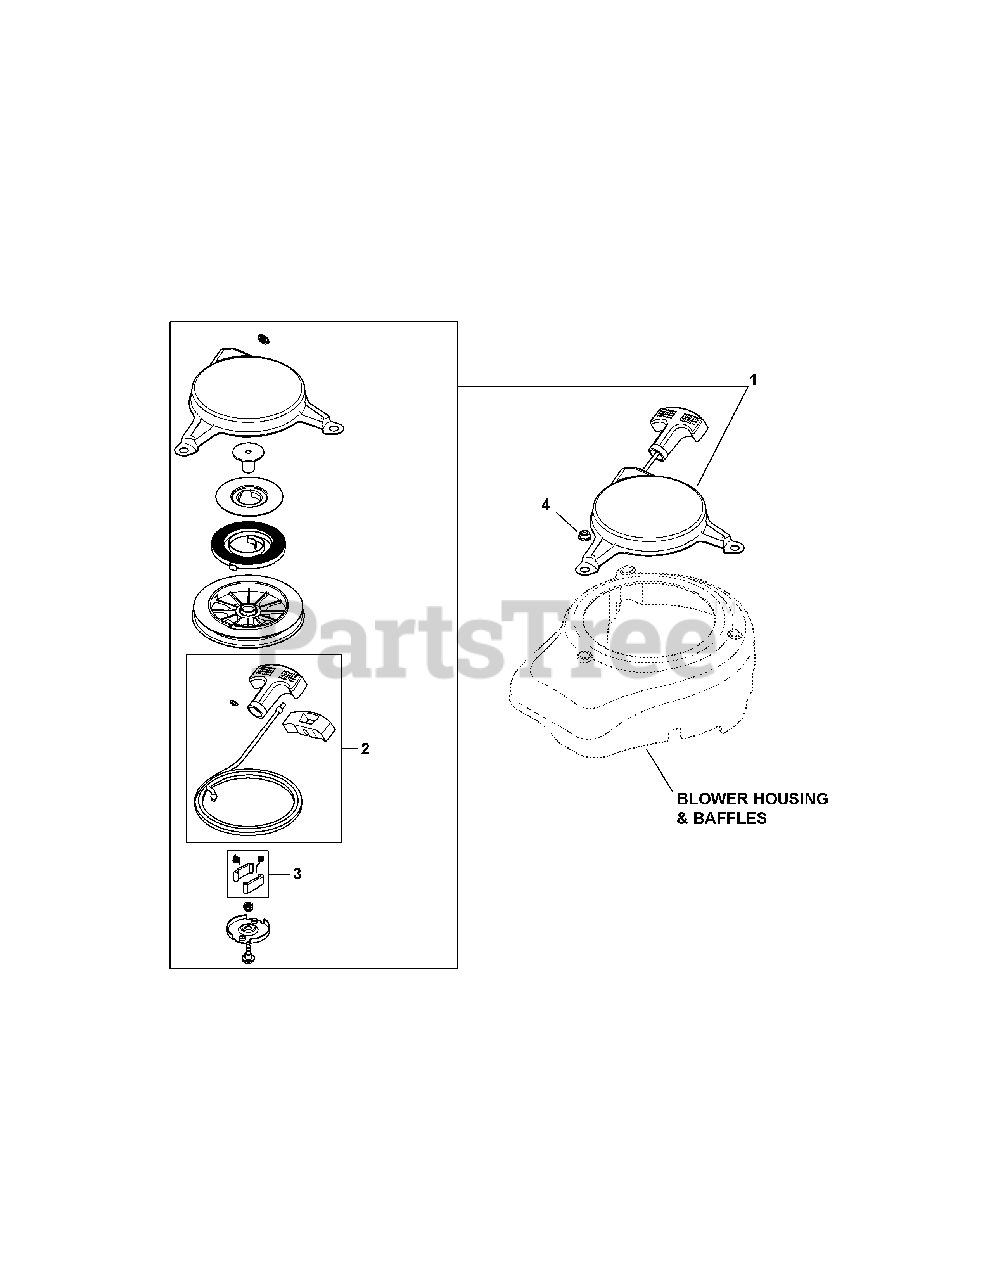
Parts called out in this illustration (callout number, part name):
1	Starter, Recoil
2	Kit, Starter Rope W/Handle
3	Kit Pawl Repair
4	Nut, Flange M6x1.0
